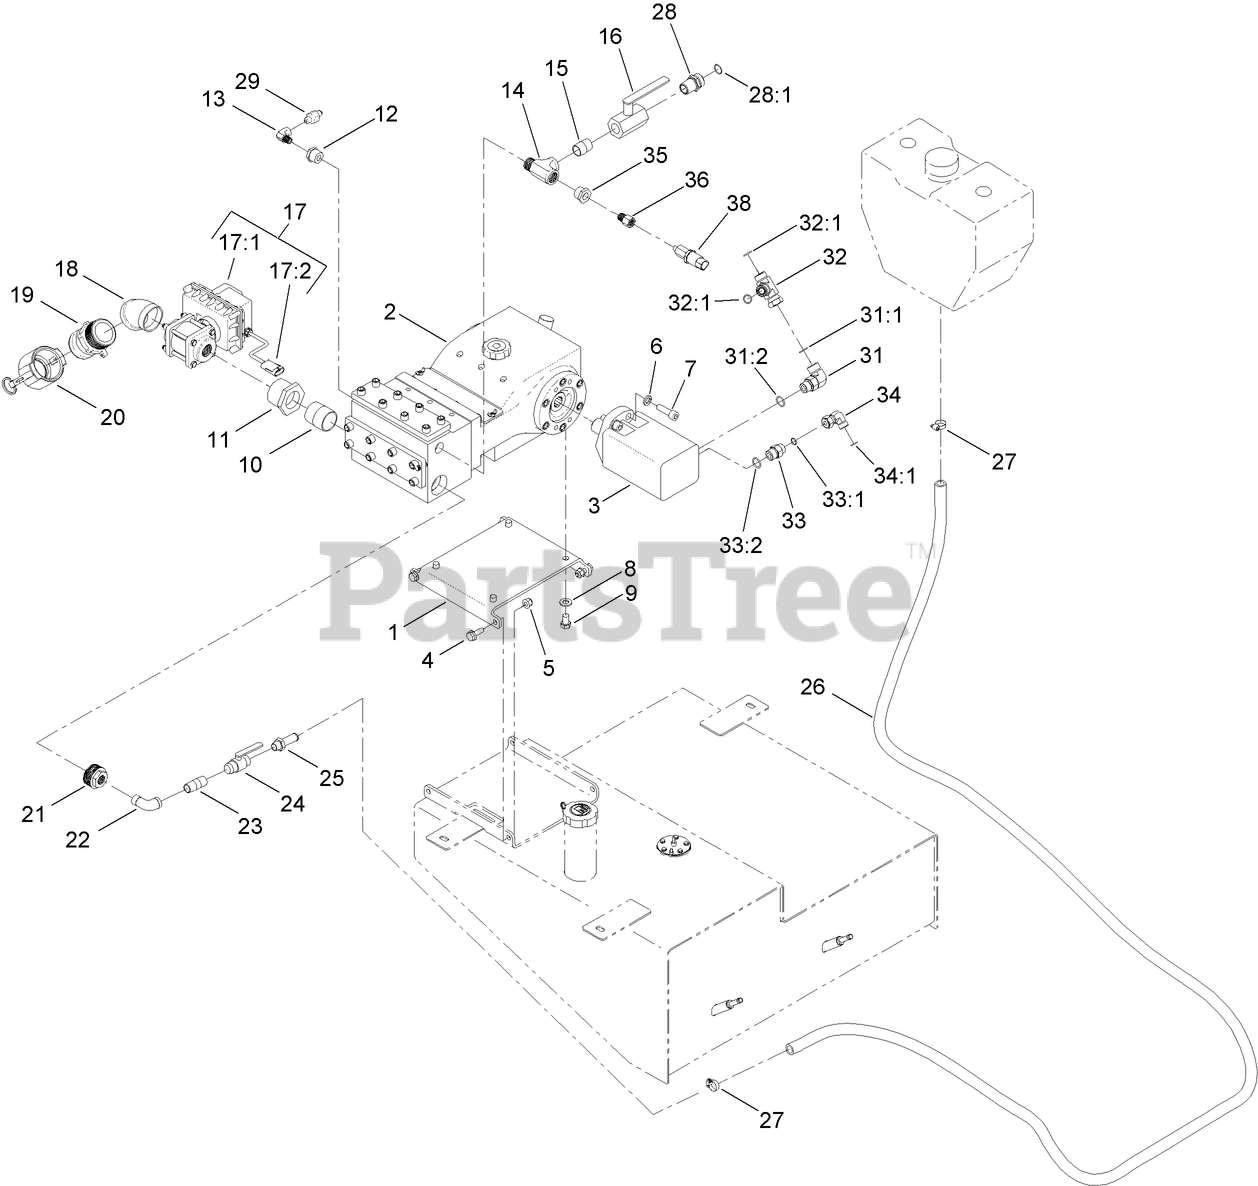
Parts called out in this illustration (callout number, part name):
1	PLATE-MOUNT, MUD PUMP
2	MUD PUMP ASM
3	HYD MOTOR ASM
4	SCREW-HHF
5	NUT-LOCK, NI
6	WASHER-LOCK
7	SCREW-HSH
8	WASHER-FLAT
9	BOLT-HH
10	NIPPLE-PIPE
11	BUSHING-REDUCER
12	BUSHING-REDUCER
13	FITTING-ELBOW-90
14	FITTING-TEE
15	NIPPLE-STRAIGHT
16	VALVE-BALL
17	2 INCH BALL VALVE ASM (ELECTRIC)
17:1	WATER SHUTOFF VALVE ASM
17:2	CONNECTOR-MALE, 3-WAY (BODY ONLY)
18	ELBOW-PIPE-45
19	ADAPTER-MALE
20	CAP-CONNECT, QUICK
21	BUSHING-PIPE, REDUCER
22	FITTING-ELBOW-90
23	NIPPLE-PIPE
24	VALVE-BALL
25	ADAPTER
26	HOSE-COOLANT
27	CLAMP-HOSE, WORM DRIVE
28	FITTING-STRAIGHT
28:1	O-RING
29	NIPPLE-CONNECT, QUICK
31	FITTING-ELBOW-90
31:1	O-RING
31:2	O-RING
32	FITTING-HYD, TEE
32:1	O-RING
33	Fitting
33:1	O-RING
33:2	O-RING
34	FITTING-HYD
34:1	O-RING
35	BUSHING-REDUCER
36	FITTING-STRAIGHT
38	TRANSDUCER (W/ISOLATOR)
